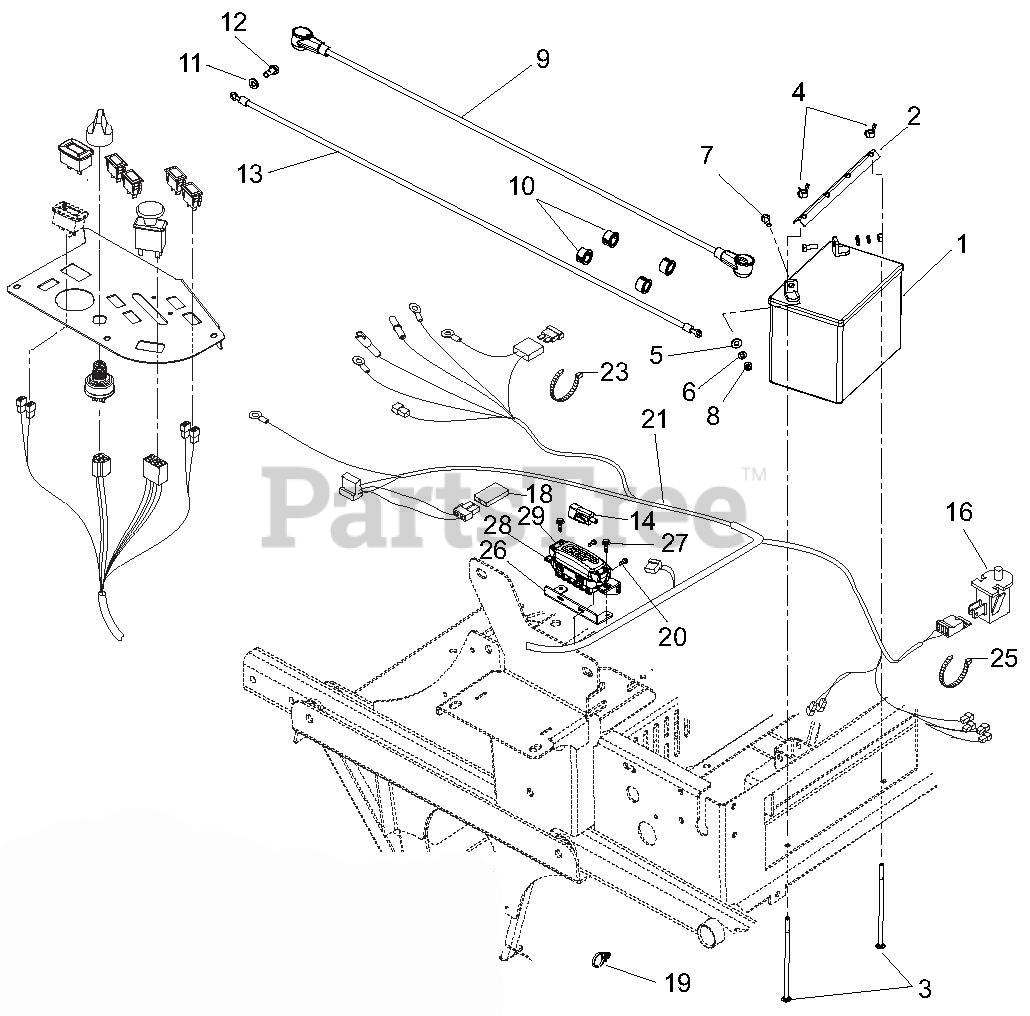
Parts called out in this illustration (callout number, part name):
1	Battery, Group 70-540 CCA
2	Hold Down
3	Bolt, Round Head Square Neck .25-20 x 7.50
4	Nut, Locking Wing .250-20
5	Washer, Flat-Steel .281 x .62 x .065
6	Washer, Locking .25 x .062 Regular
7	Bolt, Hex .25-20 x .75 Grade 5
8	Nut, Hex .25-20
9	Cable, POS Battery w/Boots 6 x 35
10	Bushing, Panel Snap .687 x .875 x .56
11	Washer, Locking .31 x .078 Regular
12	Bolt, Hex M8-1.25 x 20
13	Cable, Negative Battery 35.0"
14	Switch, Snap-In - N.O./N.O.
16	Switch, Snap Mounting
17	Fuse, 30 Amp
18	Diode, Connector Shell
19	Cable Tie with TREE .25 HOLE
20	Bolt, Hex M6-1.0X25
21	Harness, PT400 Wiring
23	Cable Tie
24	Lead, Starter Solenoid
25	Cable Tie
26	Fuse Holder Mounting Bracket
27	Screw-Tapping .25-20X.50 Hex Washer Head
28	Fuse Holder
29	Cover, Fuse Holder
